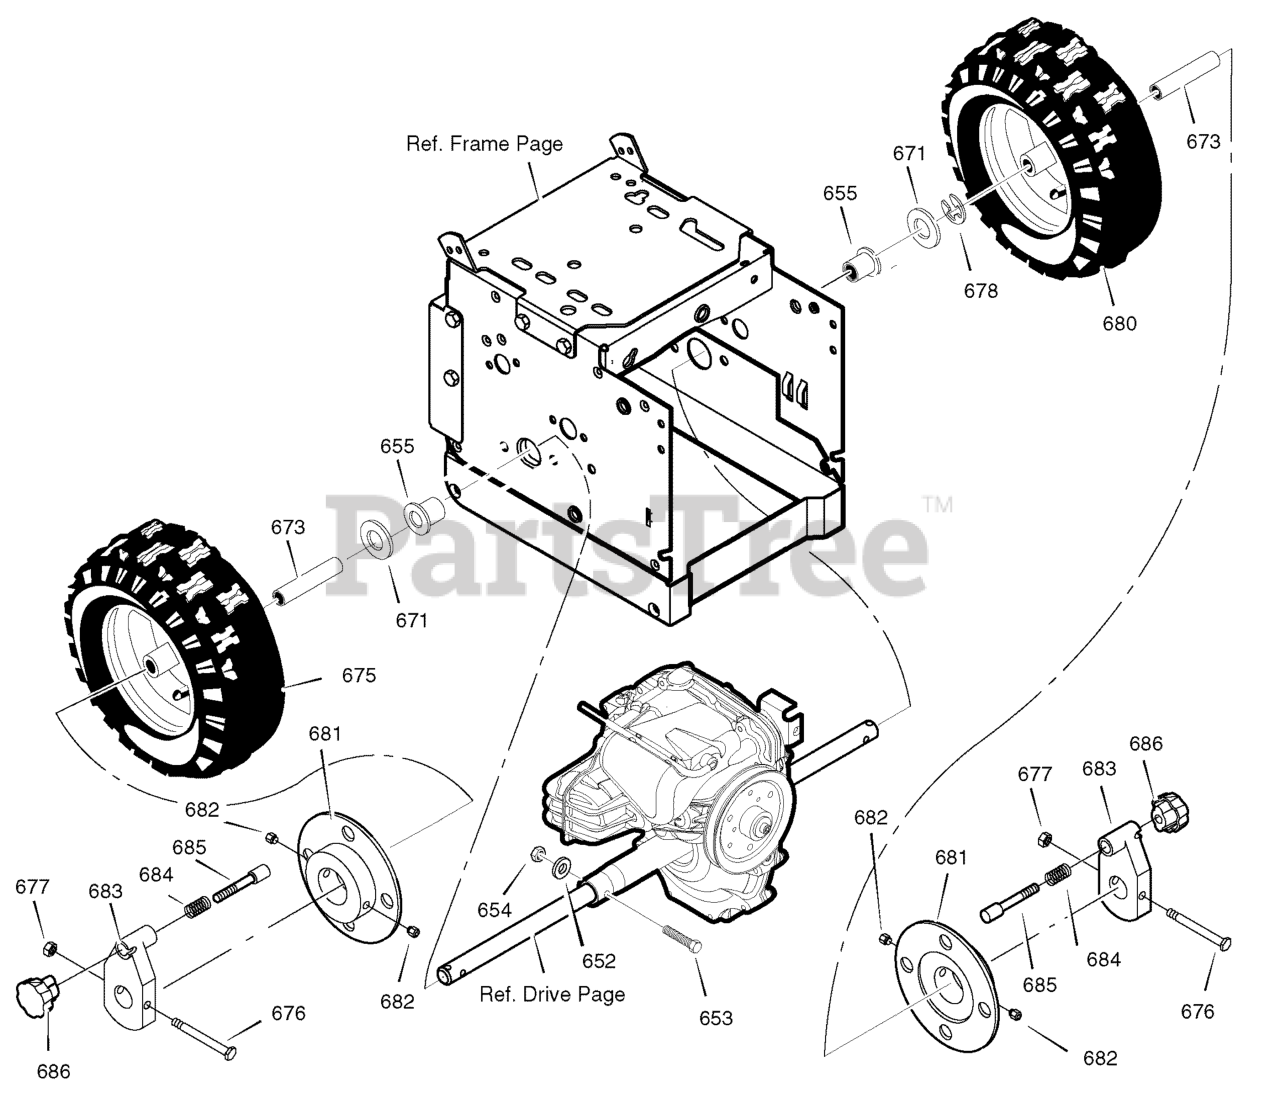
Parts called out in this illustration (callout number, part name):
652	SPACER
653	SCREW, 1/4-20X1.75
654	NUT, 1/4-20
655	BEARING, AXLE
671	FLATWASHER
673	BUSHING, WHEEL
675	TIRE & RIM, RIGHT
676	SCREW, 1/4-20X2.25
677	NUT, 1/4-20
678	RING, RET
680	TIRE & RIM, LEFT
681	DISC, WHEEL
682	SCREW
683	HUB, WHEEL LOCK
684	Spring *
685	YZ PIN, LOCK
686	KNOB *
